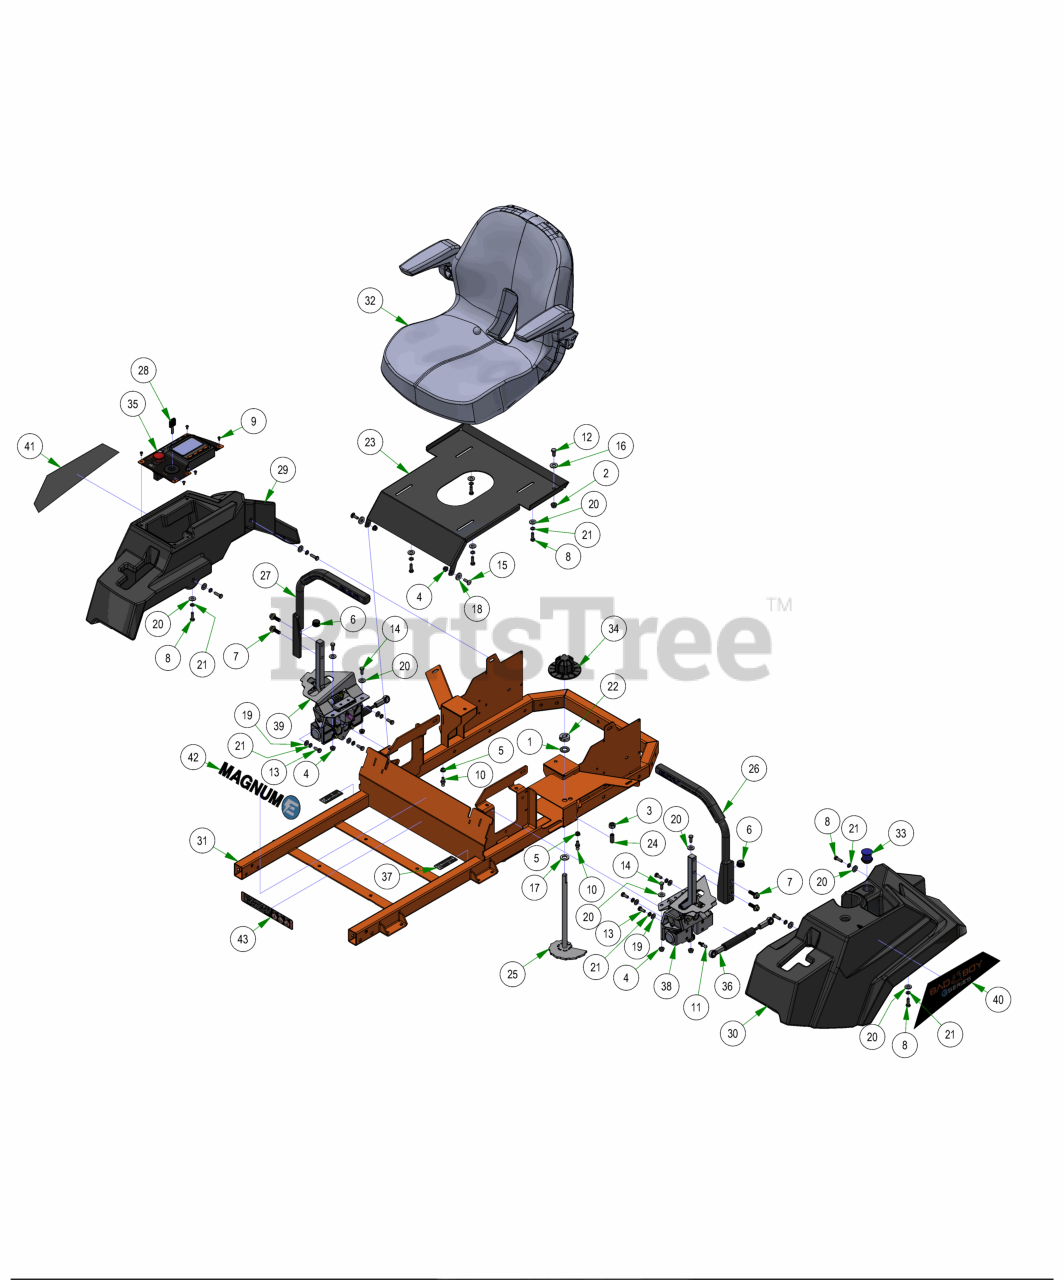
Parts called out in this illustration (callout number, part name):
1	.625 ID x 1.250 OD x .062 THK F/W Nylon
2	3/8-16 NYLON INSERT FLANGE LOCKNUT (GR.F) ZINC
3	1/2-13 HEX NUT ZINC
4	5/16-18 NYLON INSERT FLANGE LOCKNUT ZINC
5	5/16-18 HEX SERRATED FLANGE NUT HARD/ZINC
6	Snap-in Round Plug
7	M10 x 1.5mm x 30mm Flanged Hex Head Screw
8	5/16-18 X 1 HEX CAP SCREW (GR.5) ZINC
9	10-32 X 3/8 BUTTON SOCKET CAP SCREW 18-8 STAINLESS STEEL
10	10mm Damper Ball Stud-Steering
11	Ball Stud 1.36" Overall Length
12	3/8-16 X 3/4 HEX CAP SCREW (GR.5) ZINC
13	M8-1.25 X 20MM DIN 933 HEX TAP BOLT (CL 8.8) ZINC
14	5/16-18 X 3/4 HEX CAP SCREW (GR.5) ZINC
15	5/16-18 X 7/8 CARRIAGE BOLT ZINC
16	3/8 FLAT WASHER USS (1" OD) ZINC
17	.635 ID X 1.120 OD X .140 THICK FLAT WASHER NYLON
18	.360 ID X .983 OD X .120 THICK FLAT WASHER NYLON
19	1/4 USS FLAT WASHER (3/4 OD) ZINC
20	5/16 USS FLAT WASHER (7/8 OD) ZINC
21	5/16 SPLIT LOCKWASHER ZINC
22	5/8" Split Collar
23	Residential E Mower Seat Pan
24	Dial Rod Plunger
25	Residential E Mower Deck Height Dial Rod Assembly
26	E-Mower LH Steering Arm With Blue Grip
27	E-Mower RH Steering Arm With Blue Grip
28	Ignition Key
29	Residential E Mower RH Shroud
30	Residential E Mower LH Shroud
31	Residential E Mower Frame
32	2023 Electric Mower Seat
33	USB Charger
34	MZ/ZT Deck Height Dial
35	2024 MZ Electric Control Panel Assembly
36	ZT Avenger Steering Dampener
37	2018 LH/RH Steering Control Decal Roll
38	Residential E Mower LH Drive Housing
39	Residential E Mower RH Drive Housing
40	E-Mower Tank Decal LH
41	E-Mower Tank Decal RH
42	Front Cover (Magnum E) Decal
43	E Mower Danger Decal
